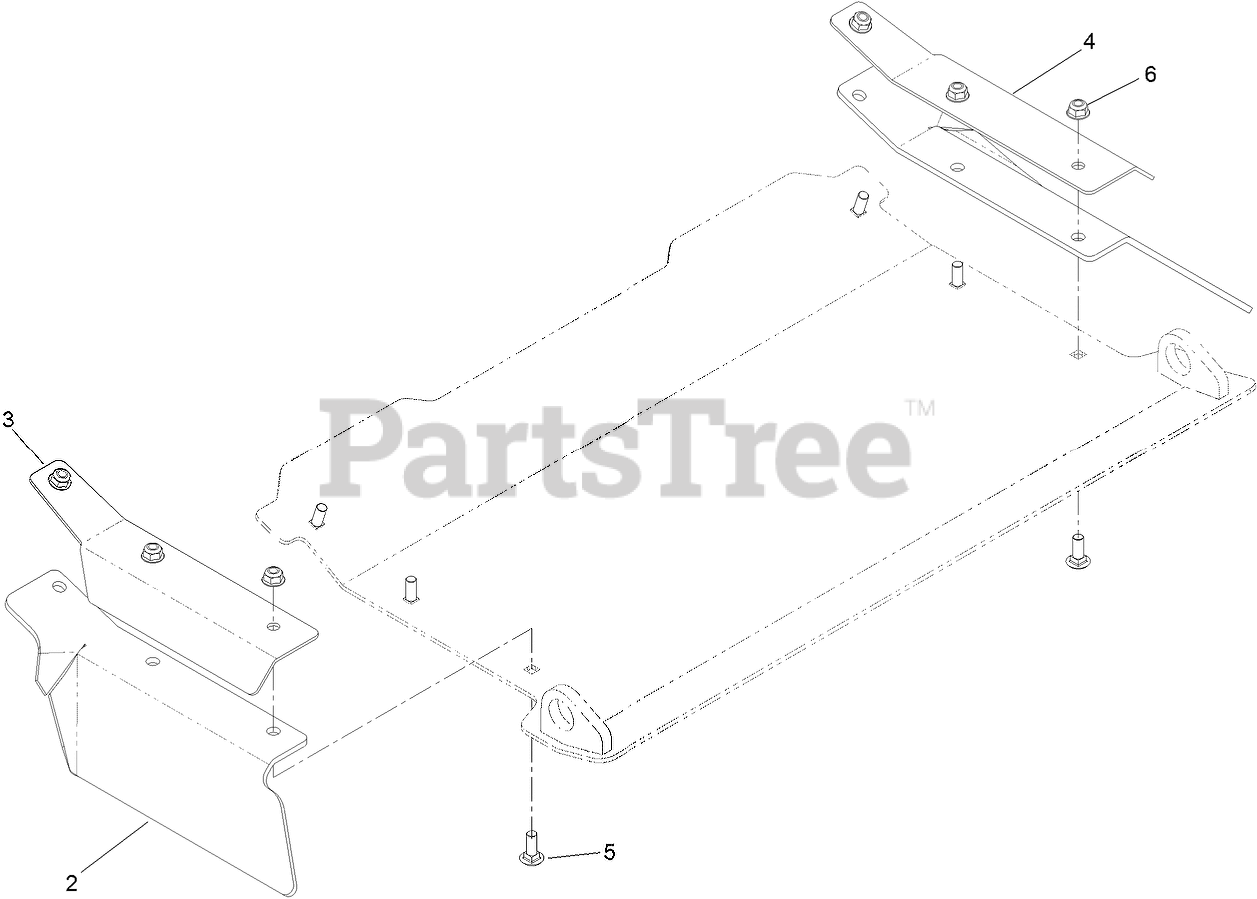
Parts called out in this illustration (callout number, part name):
2	FLAP-RUBBER
3	BRACKET-FLAP, LH
4	BRACKET-FLAP, RH
5	SCREW-CARR
6	NUT-HF, NI
